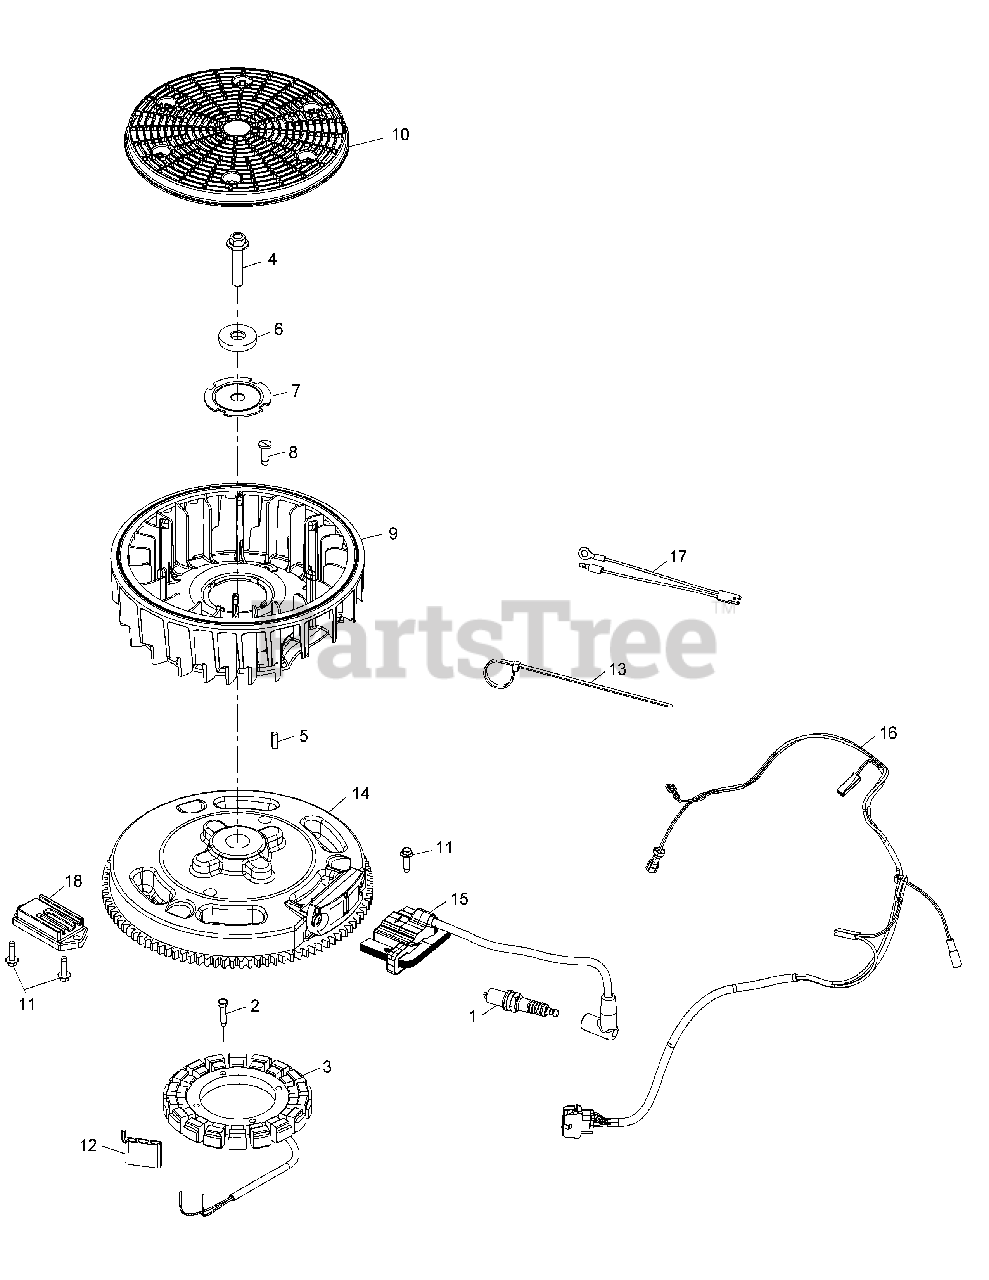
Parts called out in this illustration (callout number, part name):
2	Thread Forming Screw
3	15 Amp Stator Kit
4	Hex Flange Screw
7	Fan Mounting Plate
8	Flywheel Fan Retainer
11	Thread Forming Screw
14	Flywheel Assembly
15	Ignition Module
16	Wiring Harness
18	Rectifier Regulator
